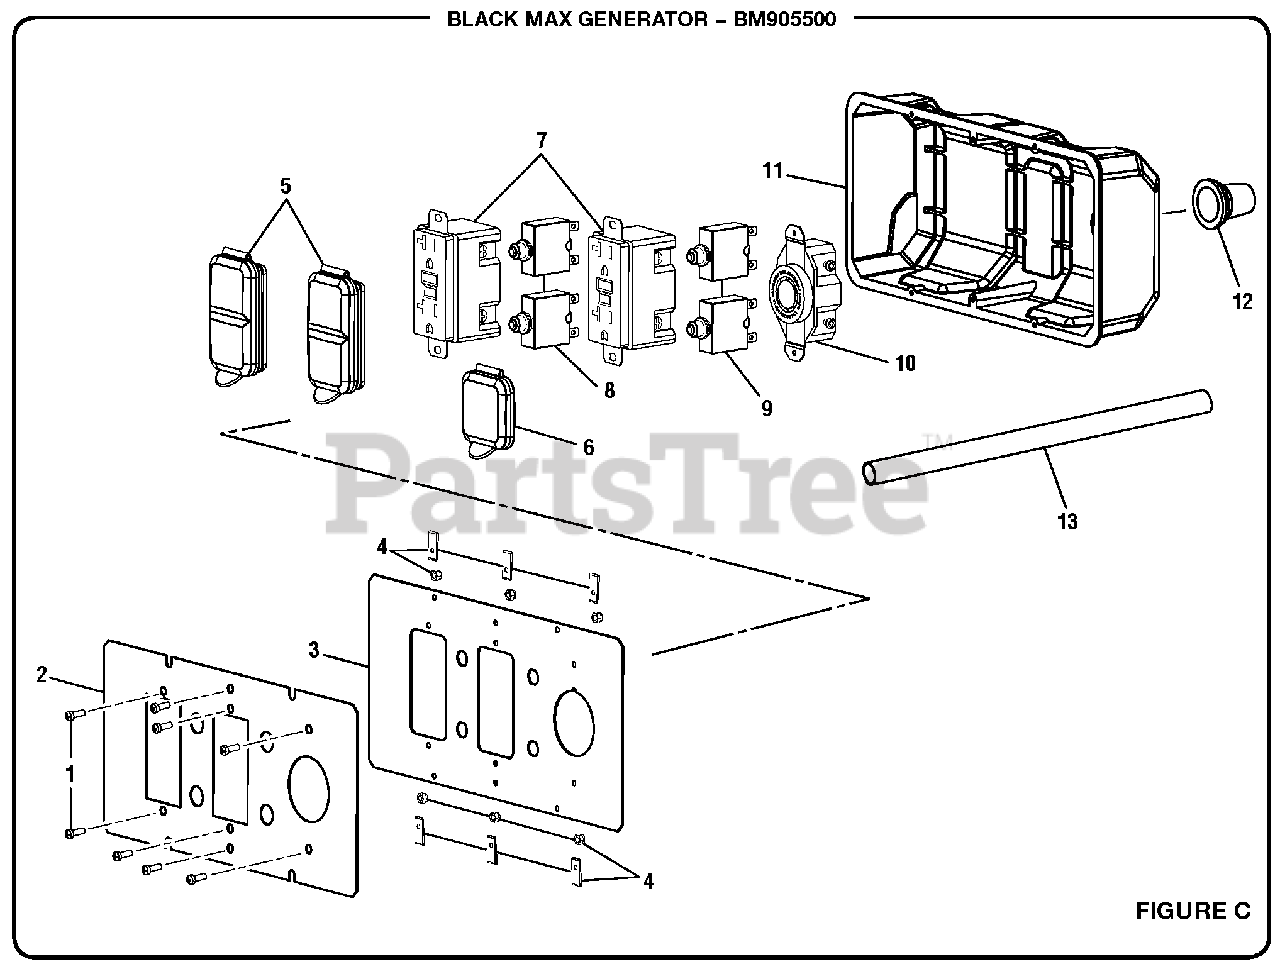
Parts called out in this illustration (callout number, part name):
1	Screw (6-20 x 3/8 in., Pan Hd.)
2	Label (Power Outlet)
3	Front Panel
4	U-Clip Nut
5	Outlet Cover (120 Volt)
6	Outlet Cover (240 Volt)
7	Duplex Receptacle (120 Volt)
8	Circuit Breaker, 20 Amp
9	Circuit Breaker, 25 Amp
10	Twist Lock Receptacle (240 Volt)
11	Control Box (Back Panel)
12	Rubber Boot
13	Wire Sleeve
